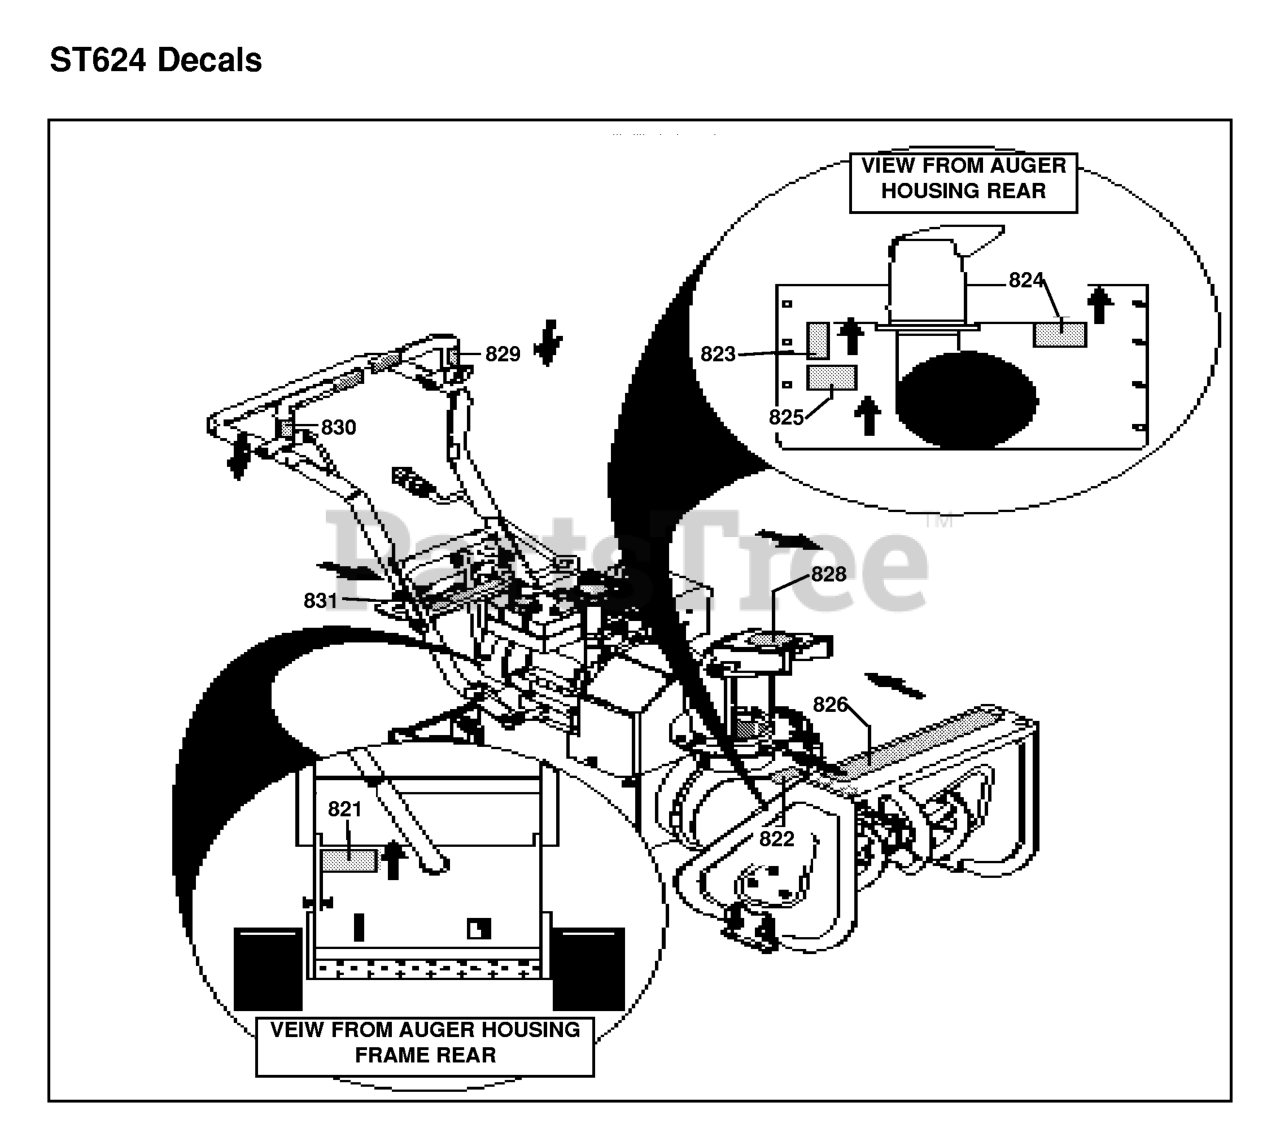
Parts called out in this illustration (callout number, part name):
822	DECAL-9" IMPELLAR
823	DECAL, DANGER CHUTE
824	DECAL-DANGER AUGER/FOOT
825	Decal, Danger English
826	DECAL, ST624E
828	DECAL, "CROWN" UPPRE CHT
829	DECAL, TRACTION DRIVE ENG.
830	DECAL, AUGER DRIVE ENGAGE
831	DECAL, GEAR SELECTOR
